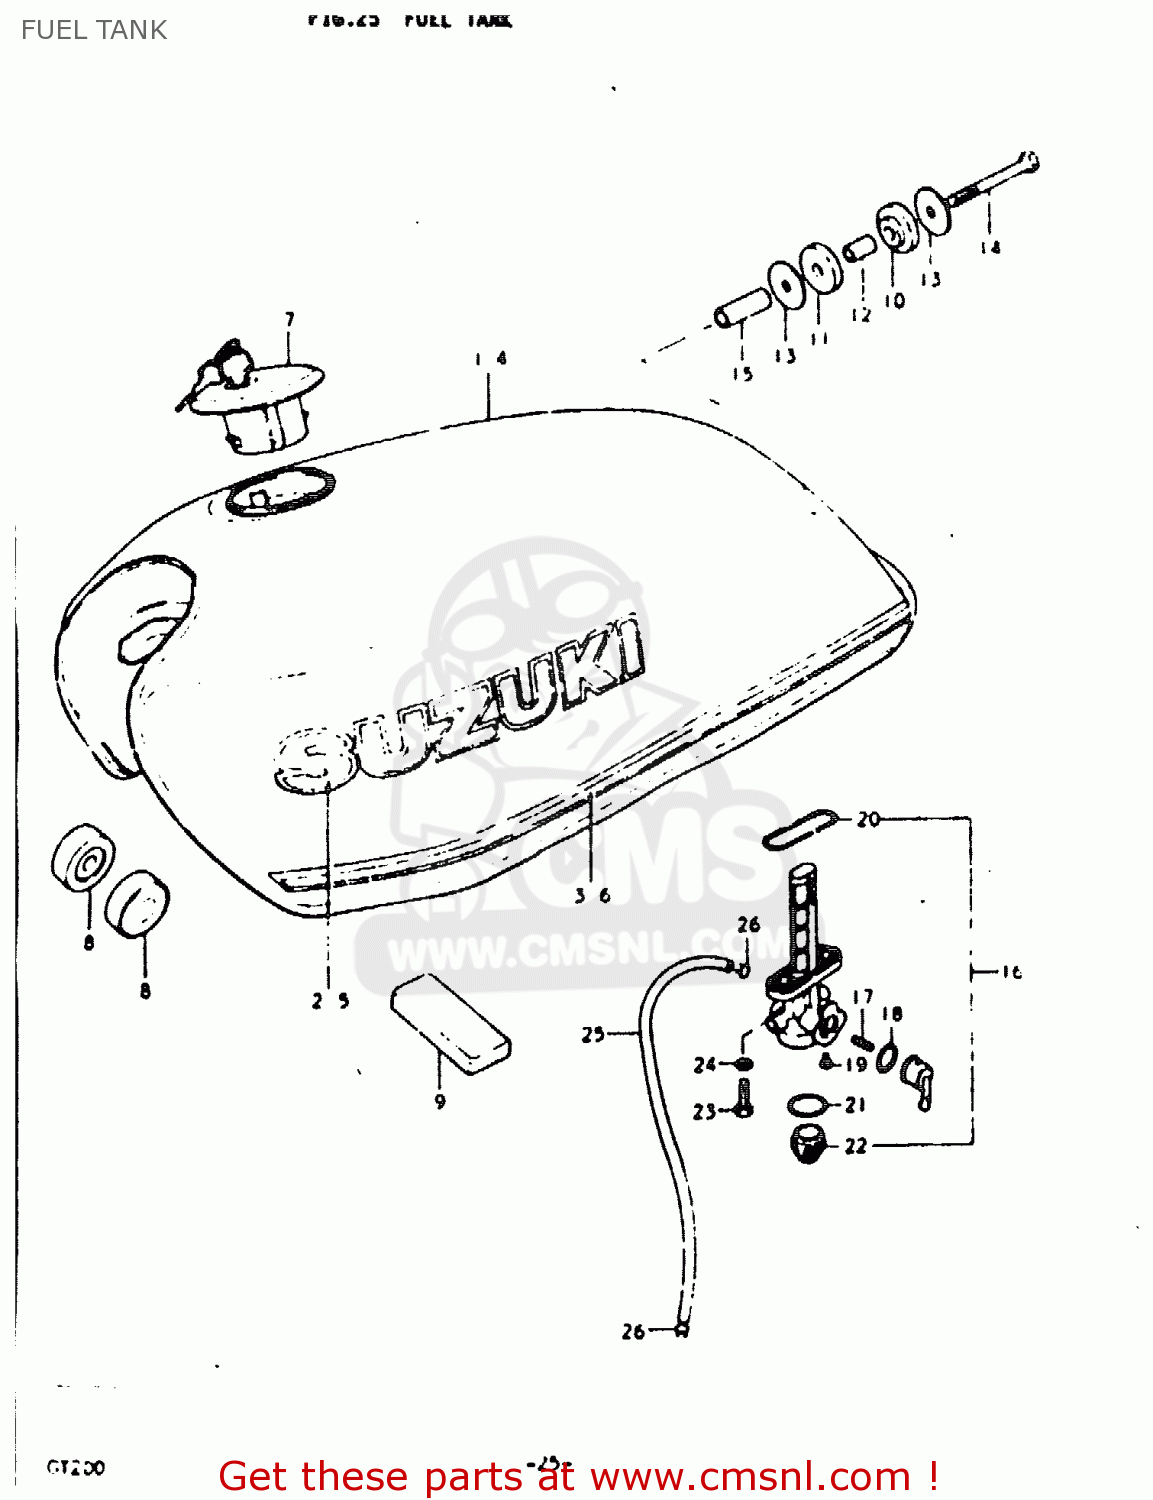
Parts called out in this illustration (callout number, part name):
1	TANK, FUEL
2	EMBLEM
3	TAPE SET
4	TANK, FUEL
5	EMBLEM
6	TAPE SET
7	CAP SET,FUEL TANK
8	CUSHION
9	CUSHION, CENTER
10	CUSHION
11	CUSHION
12	SPACER(8.5X12X19)
13	WASHER (8.5X29X1.6)
14	BOLT
15	SPACER(10.1X13X35)
16	COCK ASSY, FUEL
17	SPRING
18	O-RING
19	SCREW
20	O RING,FUEL COCK
21	GASKET,FILTER (NAS)
22	CUP,STRAINER
23	BOLT L:16
24	GASKET
25	HOSE
26	CLIP
